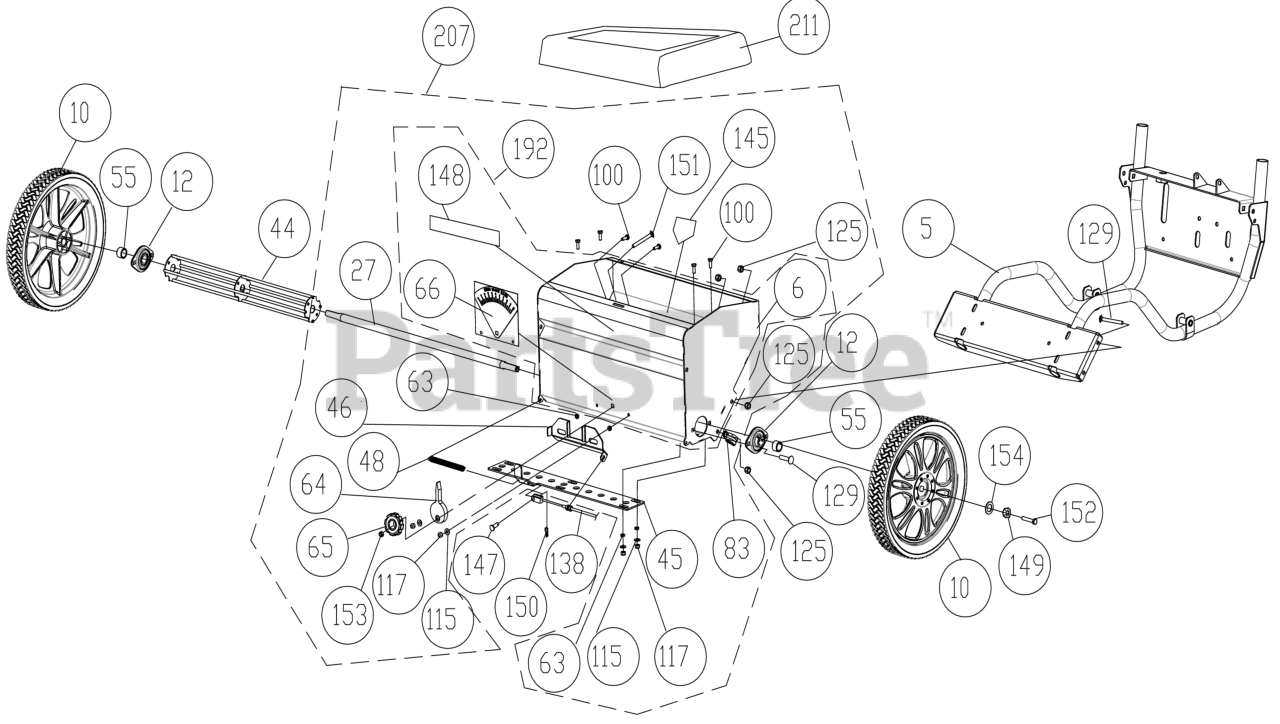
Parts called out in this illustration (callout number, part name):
5	FRAME SUPPORT OS900SP WA
6	SEED BOX WA
10	WHEEL 14" ASSY FRONT
12	BEARING & FLANGETTE ASSY .75"
27	AXLE SEED BOX
44	WHEEL PADDLE SEED WA
45	SEE: 351620
46	BRACKET CONTROL SEED RATE
48	SPRING EXTENSION .500"X5.00"
55	SPACER SEED BOX AXLE
63	SPACER SEED PLATE
64	CAM SEED RATE
65	KNOB 5/16"-18 X 5/8" FLUTED
66	LABEL SEED FLOW RATE
83	CLAMP ROUTING FUEL LINE
100	SCREWCAP 1/4"-20X3/4" HCS ZP
115	WASHER 1/4"SAE9/32"X5/8"X1/16"
117	NUT LOCK 1/4"-20 HEX Z/P
125	NUT FLANGE 5/16"-18 ZP
129	BOLT CARRIAGE 5/16"-18 X 3/4" ZP
138	CABLE CLUTCH SEEDING CONTROL
145	LABEL WARNING OPEI
147	PIN CLEVIS 1/4" X .61
148	LABEL BADGING
149	WASHER LOCK 5/16" TWISTED TOOTH HEAVY
150	PIN CLIP HITCH 0.051 X 3/4"
151	BOLT CARRIAGE 5/16"-18 X 1 1/4" ZP
152	SCREWCAP 5/16"-18X3/4" HCS ZP
153	NUT LOCK 5/16"-18 LT WT TH ZP
154	WASHER FLAT FENDER 5/16
192	SEED BOX W/LABELS
207	KIT SEED BOX OSSP SERVICE
211	SEED BOX BONNET
